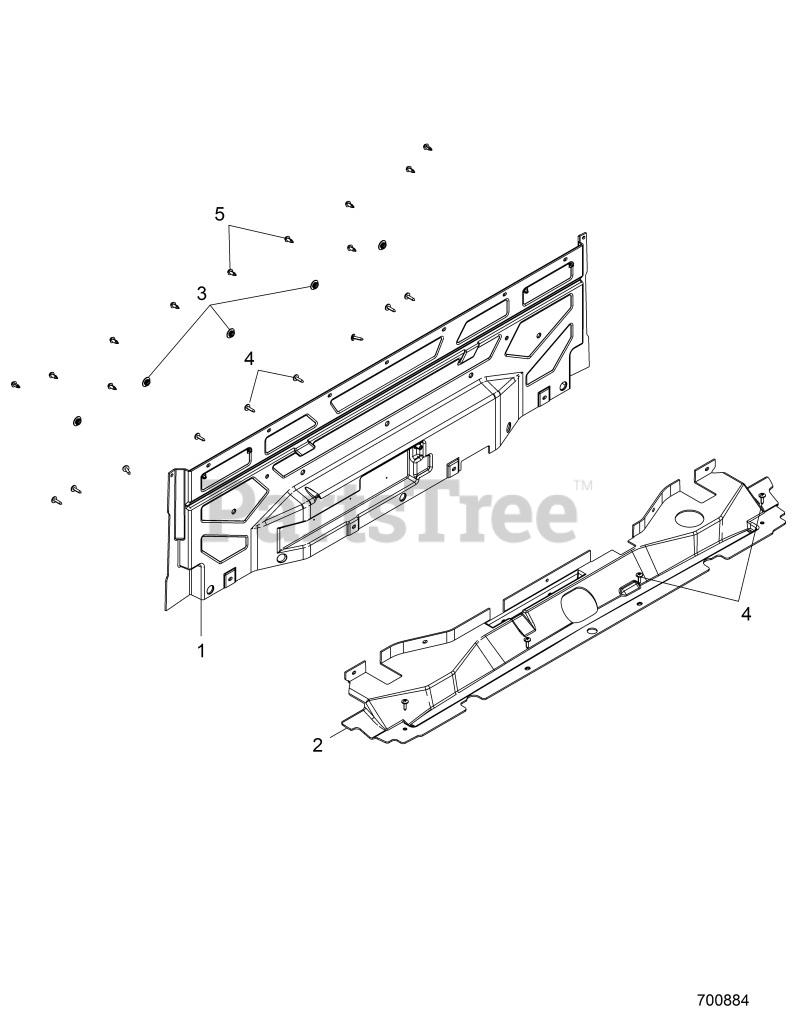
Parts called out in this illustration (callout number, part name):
1	PANEL-CLOSEOFF,REAR,BLK
2	PANEL-CLOSEOFF,LOWER,BLK
3	PLUG-COMPARTMENT
4	SCR-TXTH-M6X1.0X25 RIE
5	RIVET-TUFLOK,.315-.325X.787 (5
